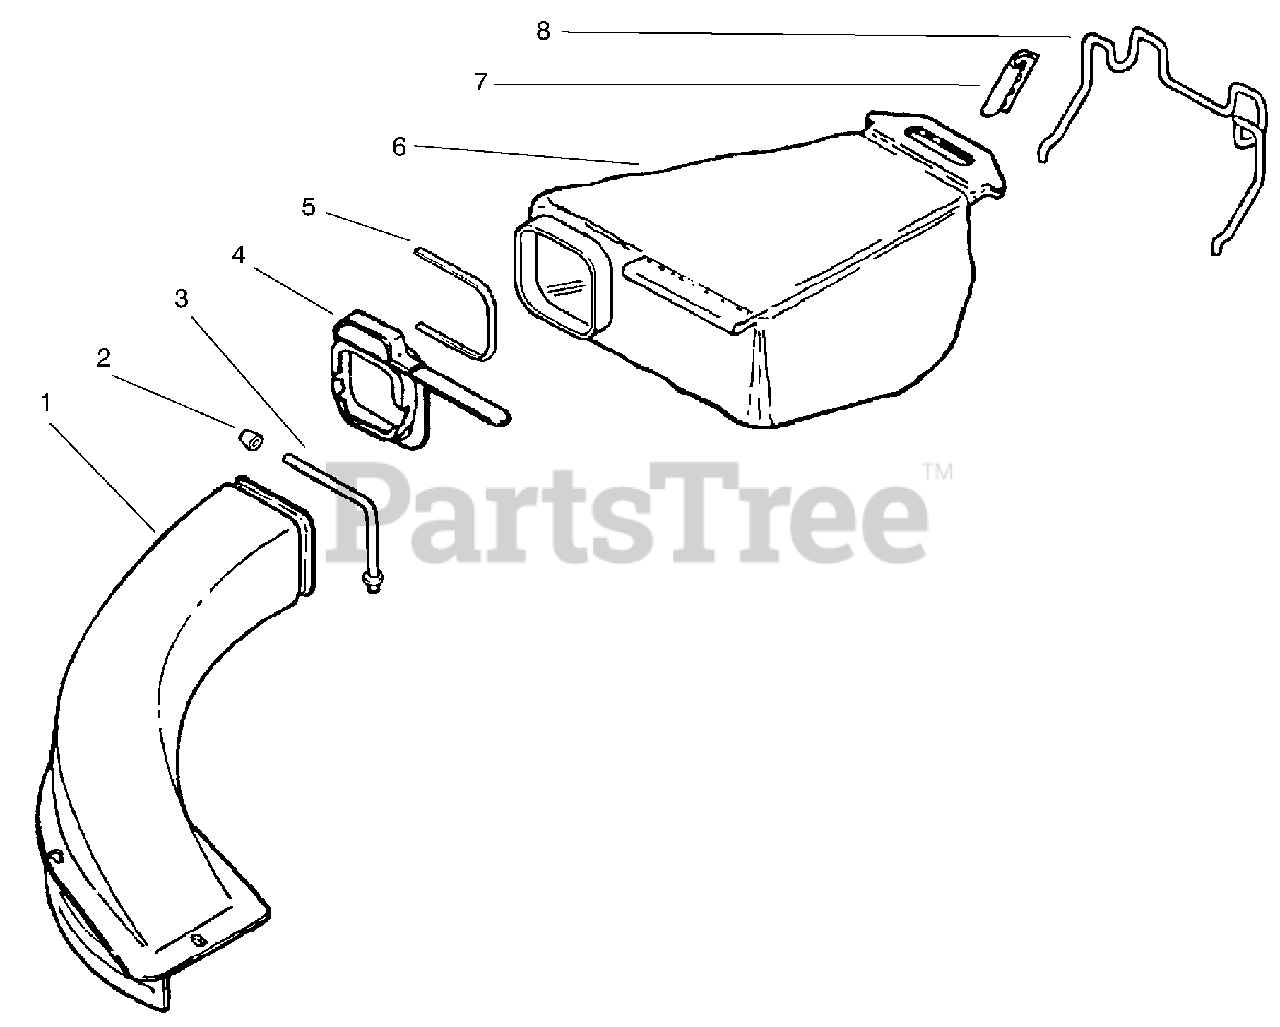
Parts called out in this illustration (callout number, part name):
1	Chute & Support Assembly (Incl. ref.# 2 & 3)
2	Nut-Cap
3	Chute Support
4	Adaptor Assembly
5	Tie Strap
6	Bag Assembly
7	Hanger Clamp
8	Narrow Hanger
